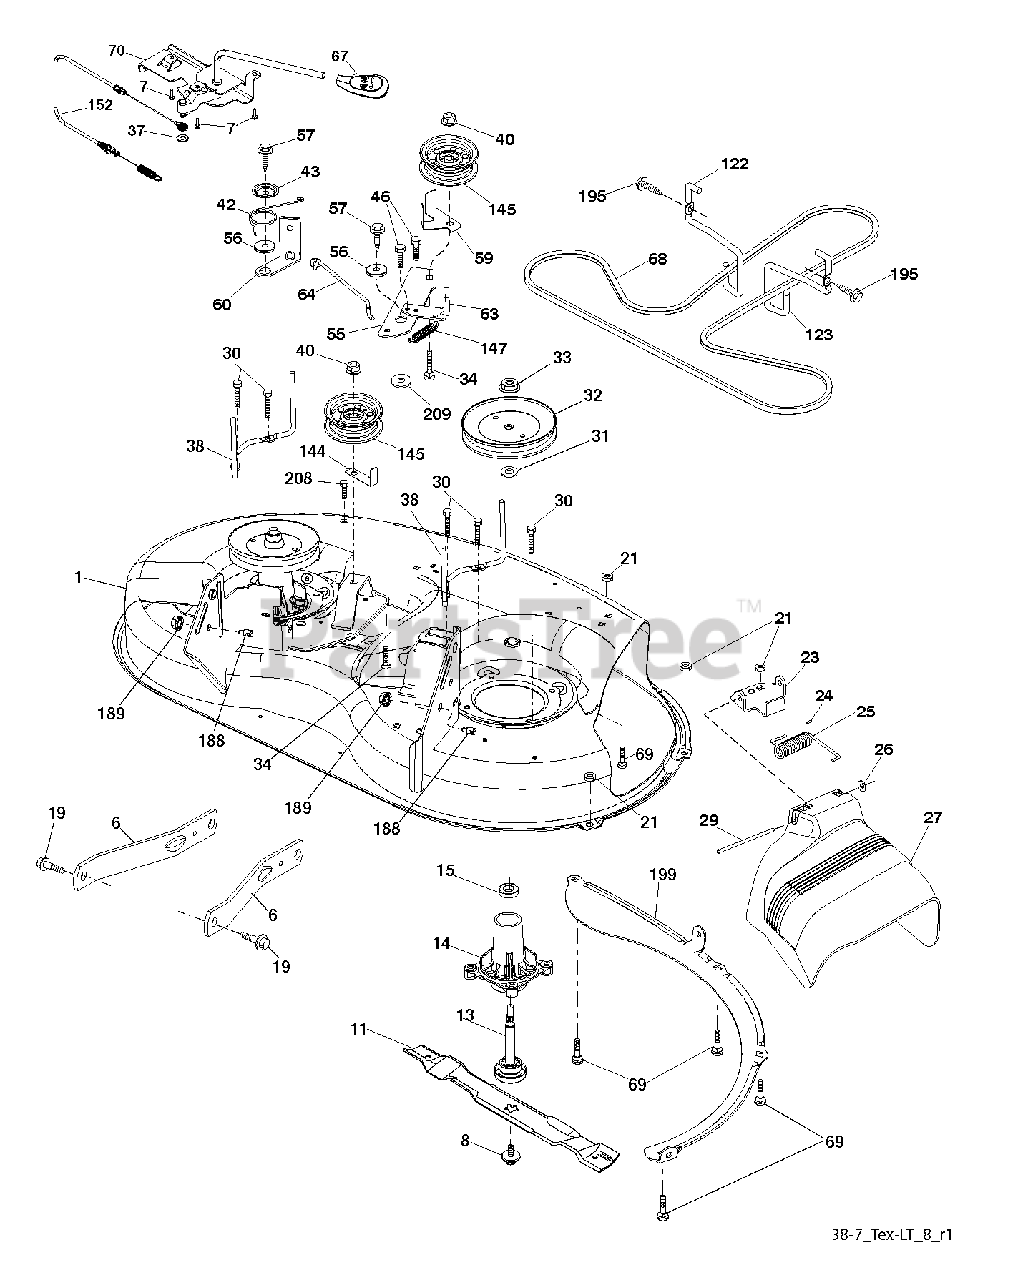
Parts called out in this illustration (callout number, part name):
6	ARM.SUSPENSION.MOWER.R
7	SCREW.#10 X 0.750.BOS (2 2)
8	BOLT.WASHER.ASM.7/16-2
11	BLADE 38" PREMIUM
13	SHAFT.ASM.MDRL.N/GREASE.38
14	HOUSING.MANDREL.4PT.
19	BOLT.SHOULDER
21	LOCKNUT
23	BRKT.DEFLECTOR.38"2005+
24	CAP-SLEEVE LT
25	SPRING.TORSION.DEFLECT
26	NUT PUSH M
27	SHIELD, DEFLECTOR
29	ROD.HINGE
30	SCREW, WASHER HEAD
31	WASHER.SPACER.MANDREL
32	PULLEY.MANDREL.5.0.PD.38"
33	NUT.FLANGE.LOCK.TOP
34	BOLT.3/8-16X1.50
38	KEEPER BELT LH MANDREL
40	NUT LOCK FLG 3/8-16 UNC
42	SPRING.TORSION.BRAKE
43	SRPING.TORSION.RETAINE
46	SCREW.1/4-20X5/8
55	IDLER.ARM
56	SPACER.RETAINER
57	SCREW 3/8-16X1
59	GUARD, BELT
60	ARM BRAKE MOWER RH 38"
63	ARM BRAKE MOWER RH
64	LINK BRAKE
67	HANDLE.CLUTCH.CABLE.LT
68	Drive Belt, 38"
69	BOLT
70	CLUTCH.ASM.MANUAL.LT.TEX
122	KEEPER BELT ENGINE LH
123	KEEPER BELT RH
144	KEEPER BELT
145	PULLEY.IDLER.48"PRIMARY
147	SPRING RETURN
152	CABLE.CLUTCH.MANUAL.
188	STUD.FASTNER.W/ANTI-ROTATE
189	NUT LOCK HEX FLANGE 5/16-18
195	SCREW, 3/8-16X3/4
199	BAFFLE.VORTEX.FRONT.38"
208	SCREW 3/8-16X1/2
209	WASHER 12/32X2X10GA
